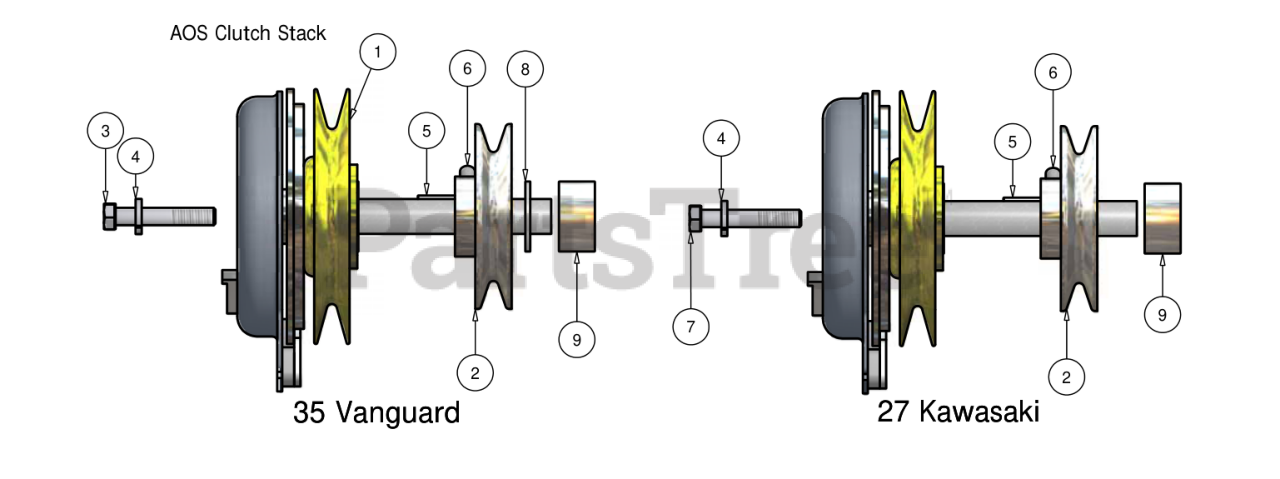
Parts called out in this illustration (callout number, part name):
1	Clutch Assembly
2	4 3/4" Motor Pulley
3	7/16" x 2 1/2"Fine Thread Bolt
4	7/16" Lock Washer
5	1/4" x 1" Key
6	3/8" Set Screw
7	10mm x 552 Bolt
8	1 1/8" Flat Spacer
9	1 1/8" Collar Spacer
